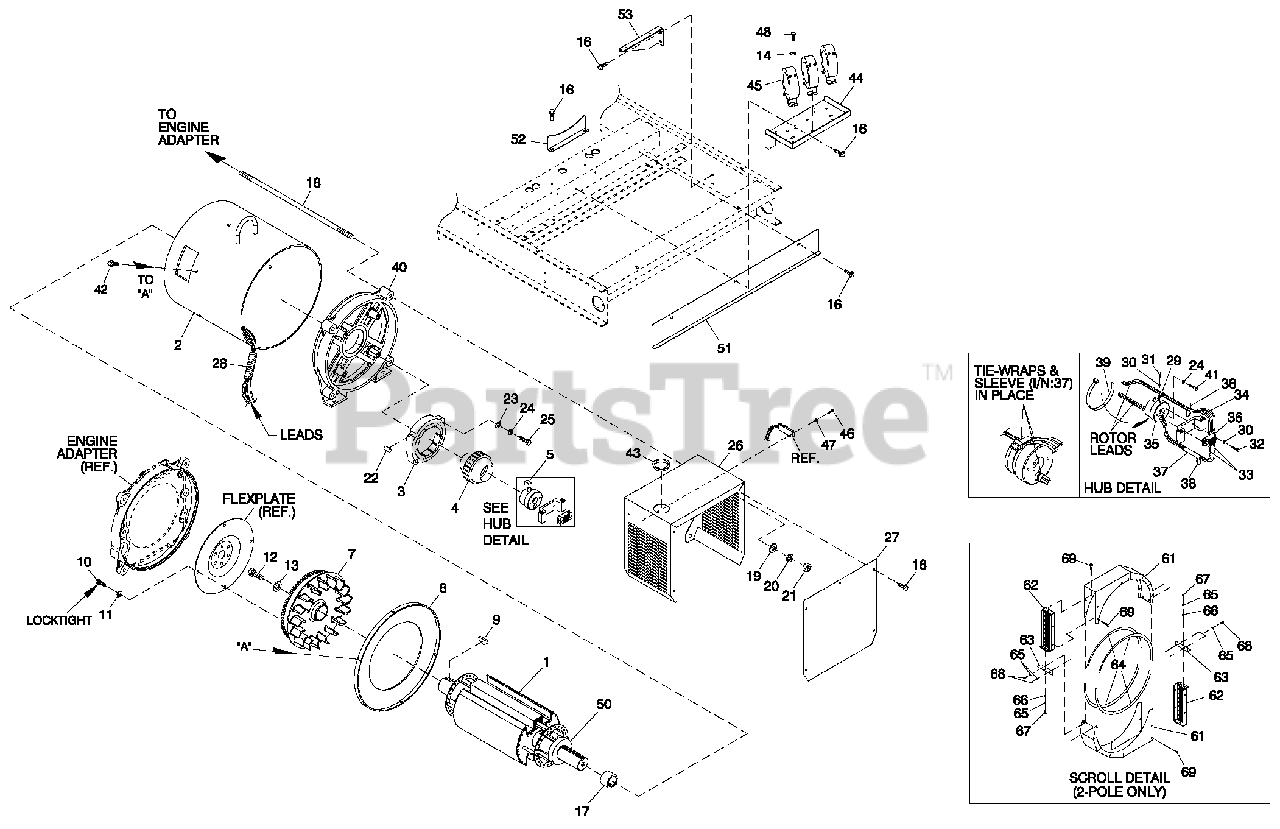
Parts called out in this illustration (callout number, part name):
1	ASSY ROTOR 390 2P 150K BRSHLS
2	ASSY STATOR 390 2P 150K BRSHLS UL
3	EXITER FIELD 2" LG SPD CONN
4	ASSY EXCITER 2.0" STACK 2P
5	KEY SQ 3/8 X 3-1/4 STEEL
7	ASSY FLYWHEEL CPL
8	RING PRESSURE 390 STATOR CAN
9	KEY WOODRUFF #E
10	SCREW SHC M10-1.5X 16 G10.9
11	WASHER LOCK M10
12	SCREW HHC M16-2.0X45G8.8
13	WASHER FLAT .688 ID X 3.25 OD
14	WASHER FLAT 1/4-M6 ZINC
15	WASHER LOCK M6-1/4
16	SCREW THF M6-1 X 16 N WA Z/JS
17	COLLAR SLIP FIT 390 MM
18	STUD M14-2.0X 760 G5 ZINC
19	WASHER FLAT M14
20	WASHER LOCK M14
21	NUT HEX M14-2.0G8YEL CHR
22	PIN DOWEL 1/2 X 1-1/4
23	WASHER FLAT M12
24	WASHER LOCK M12
25	SCREW HHC M12-1.75X 80 G10.9
26	SHIELD ALT EXCITER 390
27	COVER EXCITER SHIELD
28	CONDUIT FLEX 1.25" ID
29	CLAMP VINYL .312 X .203 Z
30	WASHER SHAKEPROOF INT #8
31	SCREW HHM # 8-32X3/8
32	SCREW HHM # 8-32X7/8
33	LUG RT-ANG #10/10-12
34	BRIDGE SUPPORT DIODE 15"
35	CAP END ROTOR 390MM
36	ASSY BRIDGE RECTIFIER
37	SLEEVING UL#0 .330 ID (3" LG)
38	TIE WRAP UL 3.9" X . 10" BLK
39	TIE WRAP UL 17.7 X .35 BLK HT
40	REAR BEARING CARRIER
41	SCREW HHC M12-1.75X 60 G10.9
42	SCREW 1/4-20 X 5/8" TAPTITE SS
43	BUSHING SNAP SB-2.5-31
44	MOUNT CT'S 5.4L100KW
45	TRANSFORMER
46	SCREW PHTT #6-32X1/2 ZYC
47	WASHER LOCK #6
48	SCREW HHC M6-1.0X 20 G8.8
49	NUT HEX M6X 1.0 G8YEL CHR
50	BEARING BALL 6212 SEALED
51	SHROUD LOWERALTERNATOR EXCITR
52	SHROUD CENTER ALTERNATR EXCITR
53	SUPPORT CONBOX TRANSFER SWITCH
60	ASSY SCROLL 390 X 60MM CPL
61	SHROUD ALT SHEET METAL CPL 2P
62	SCREEN, 390 SAE ALT 60MM WIDE
63	BRACKET SAE SCROLL TENSIONER
64	VINYL TRIM 1/8" GAP
65	WASHER, SPLIT 1/4" -M6
66	WASHER FLAT 1/4ZINC
67	SCREW HHC M6-1.0 x 2 5 LG
68	SCREW HHC M6-1.0X16G8.8
69	SCREW SWAGE 1/4-20 X 1/2 Z/YC
